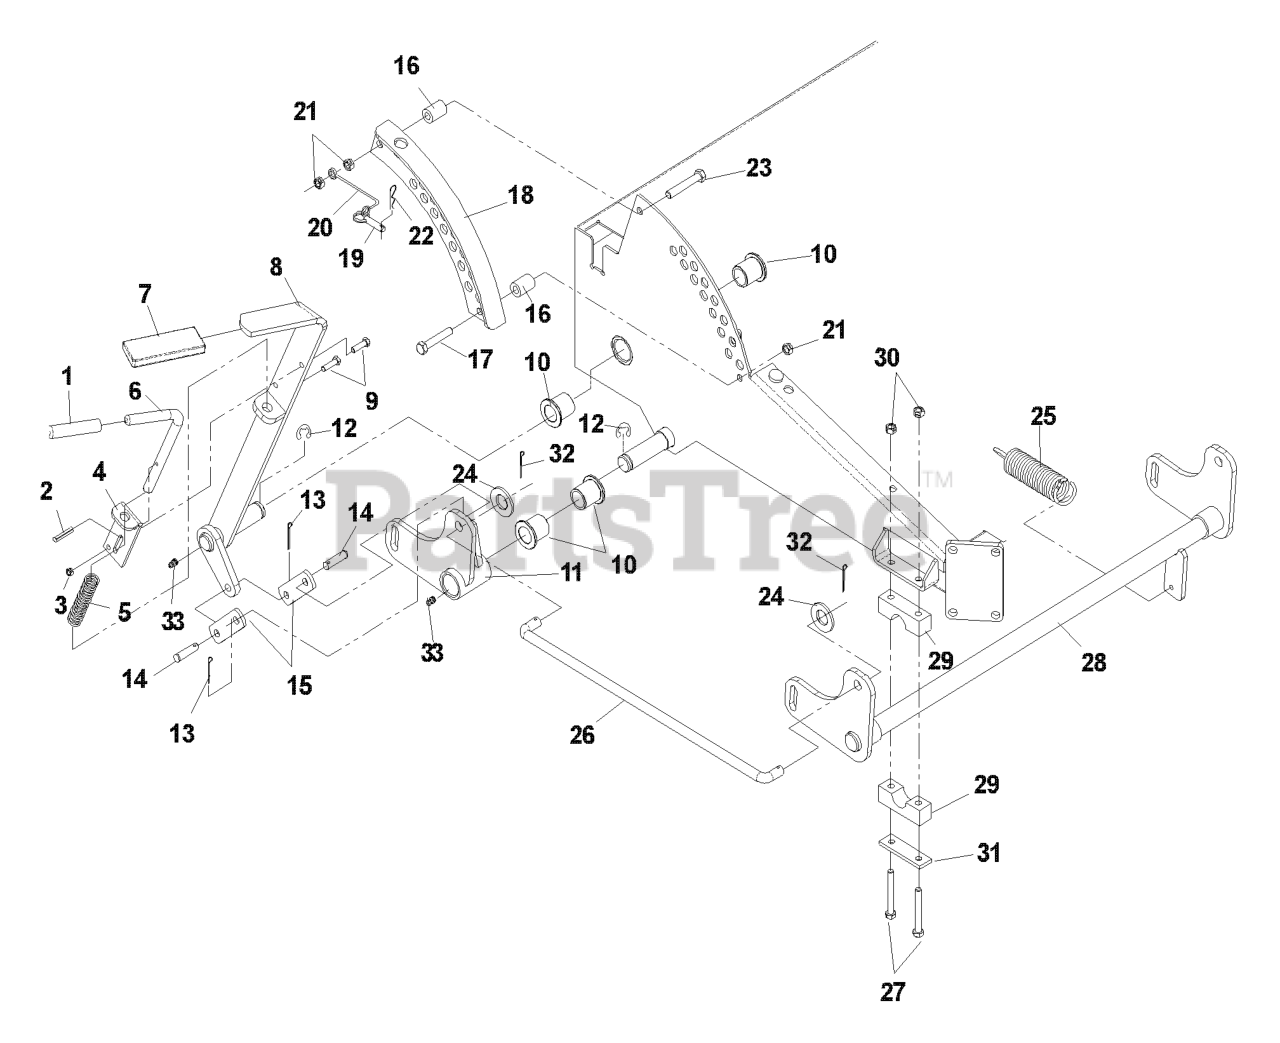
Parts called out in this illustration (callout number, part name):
3	NUT 1/4C CENTER LOCK
4	PIN MT, UPPER
8	LIFT LEVER WELDMENT
9	HCS 1/4C X 3/4 HCS
10	BUSHING, FLANGED
11	BELLCRANK, RR-BLACK
12	E-RING 7/8
13	RP_COTTER PIN 1/8 X 3/4
14	CLEVIS PIN 3/8 X 1 1/8
17	HCS 3/8C X 2
18	ADJUSTMENT PLATE
21	NUT 3/8-16 NYLOC
22	HAIRPIN #4
23	HCS 3/8C X 2 1/2
24	BUSHING
26	DECK LIFT LINK
27	HCS 5/16C X 2-3/4
28	LIFT SHAFT
29	PILLOW BLOCK
30	NUT 5/16 NYLOC
31	REINFORCEMENT BAR
32	COTTER PIN
33	ZERK
